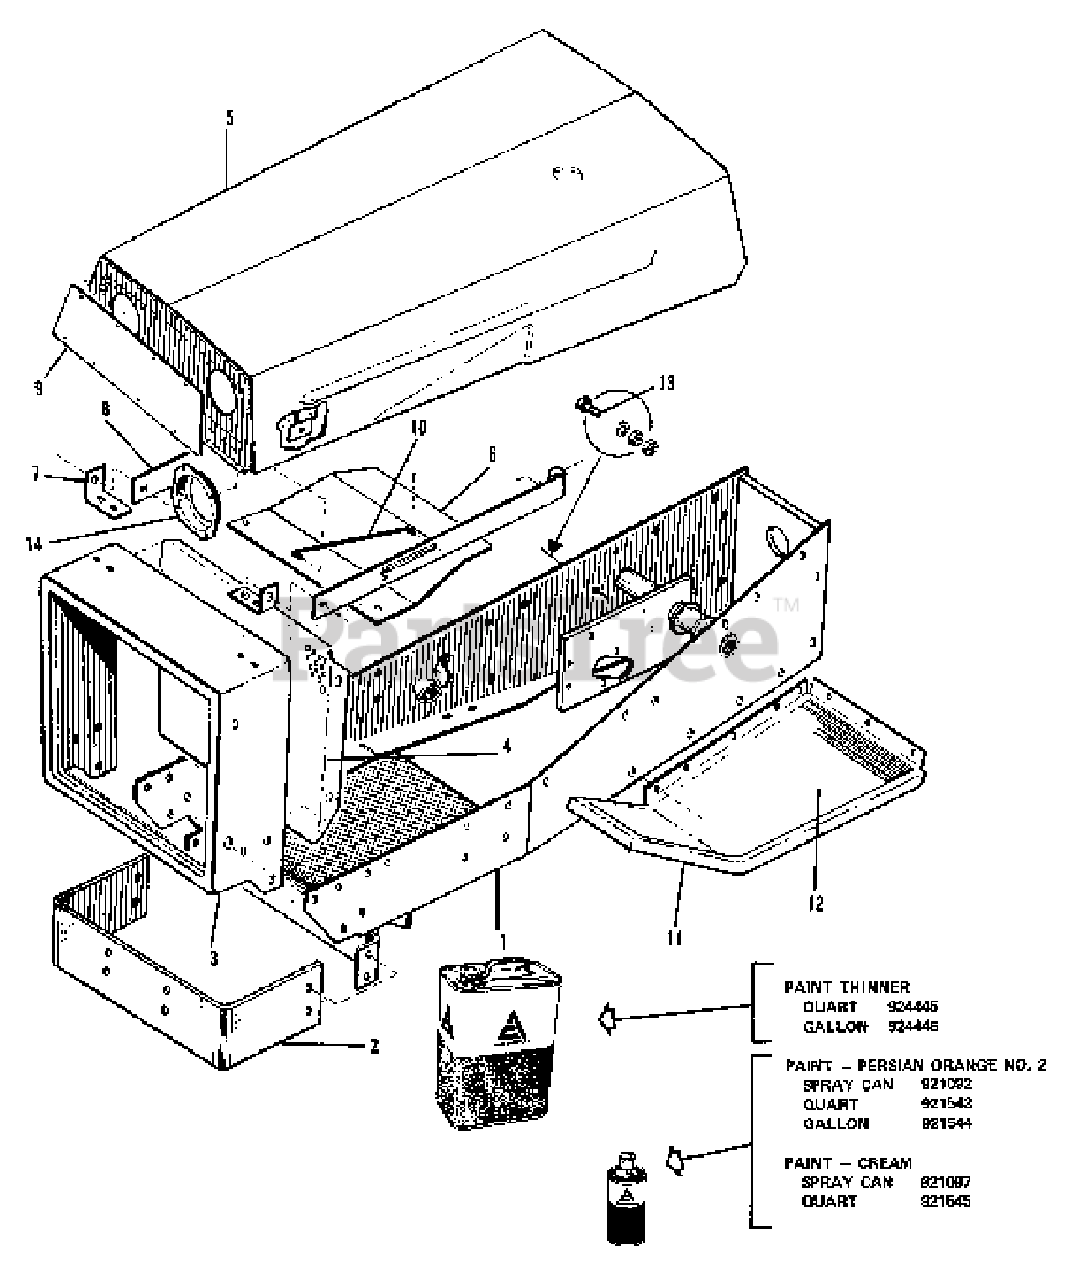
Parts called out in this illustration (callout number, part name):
1	FRAME ASSEMBLY, Main
2	BUMPER, Front
2	CAPSCREW, Hex Head, 3/8 NC x 7/8
2	LOCKWASHER, 3/8
2	NUT, 3/8 NC
3	HOUSING ASSEMBLY, Grille
3	CAPSCREW, Hex Head, 5/16 x 3/4
3	LOCKWASHER, 5/16
3	NUT, 5/16
3	WASHER, Plain, 11/32 x 1 x 10 GA
4	INSERT, GRILLE
4	CAPSCREW, Hex Head, 1/4 NC x 5/8
4	WASHER, 17/64 x 1 x 16 GA
4	LOCKWASHER, 1/4
4	NUT, 1/4 NC
5	HOOD ASSEMBLY
6	SHIELD, Engine
7	BRACKET, Grille Brace
7	CAPSCREW, 5/16 NC x 5/8
7	LOCKWASHER, 5/16
7	NUT, 5/16 NC
8	BRACE, Grille R.H. (Breakerless Ignition System)
8	BRACE, Grille R.H. (Breaker Point Ignition System)
8	BRACE, Grille L.H.
8	CAPSCREW, 5/16 NC x 3/4
8	LOCKWASHER, 5/16
8	NUT, 5/16 NC
8	WASHER, 5/16
9	COVER, HEADLIGHT (All Models Except 312-H, 314-D & 314-H)
9	SCREW, Round Head #10 NC x 3/8
9	LOCKWASHER, #10
9	NUT, #10 NC
10	ROD, HOOD LIFT
10	WASHER, 17/64 x 5/8 x 18 Ga.
10	PIN, Cotter 3/32 x 1/2
11	FOOT REST, R.H.
11	FOOT REST, L.H.
11	CAPSCREW, 5/16 NC x 5/8
11	LOCKWASHER, 5/16
11	NUT, 5/16 NC
12	PAD, Foot, L.H.
12	PAD, Foot, R.H.
13	CAPSCREW, 1/4 NC x 3/4
13	LOCKWASHER, 1/4
13	NUT, Hex, 1/4 NC
13	NUT, Lock, 1/4 NC
14	BRACKET, HEADLIGHT SUPPORT (312-H & 314-H Models Only)
14	SCREW, Round Head, #10 NC x 3/8
14	LOCKWASHER, #10
14	NUT, #10 NC
